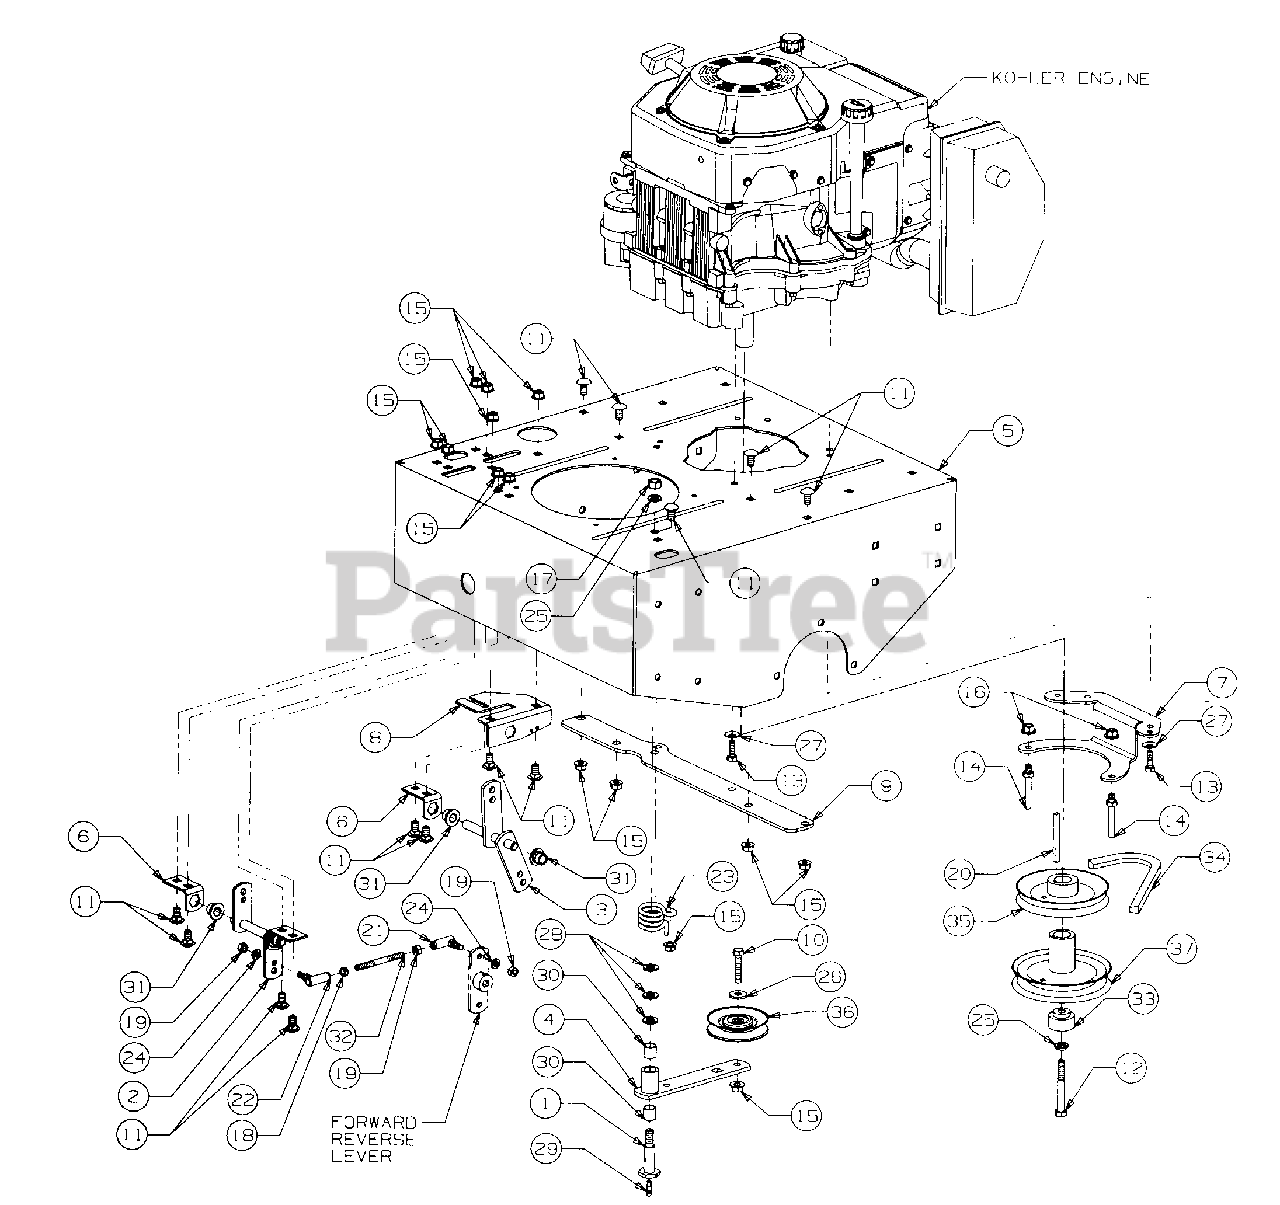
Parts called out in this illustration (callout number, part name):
1	Bolt, Shoulder
2	Lever, F/R Control
3	Lever, PTO Engagement
4	Arm Assy, Idler [Includes Ref No. 30 (Qty 2)]
5	Deck, Engine Mtg
6	Bracket, Lever Angle
7	Retainer, Belt Guide
8	Plate, Engagement Lever Mtg
9	Stiffener
10	Screw, Hex Cap, 3/6-16 X 1.75 Lg
11	Bolt Sht Nk Carriage, 3/8-16 X .75 Lg GR5
12	Screw, Hex Cap, M10 X 1.5 X 80 mm Lg
13	Screw, Hex Cap, M8 X 1.25 X 25 mm Lg
14	Stud, 3/8-16 X 2.68 Lg
15	Nut, Hex Flanged Lock, 3/8-16
16	Nut, Hex Flange Lock, 3/8-16 GR5
17	Nut, Hex, 7/16-14 GR5
18	Nut, Hex Jam, 5/16-24 LH Thread
19	Nut, Hex, 5/16-24 GR5
20	Key, Square, 1/4 X 3.0 Lg
21	Ball Joint, 5/16-24
22	Ball Joint, 5/16-24 LH Thread
23	Spring, Torsion
24	Washer, Lock, 5/16
25	Washer, Lock, 7/16
26	Washer, Special, .378 X 1.00 X .125 Thk
27	Washer, Bell, .340X .872 X .060 Thk
28	Washer, Flat, .469 X .875 X .105 Thnk
29	Fitting, Lube
30	Bearing, Sleeve
31	Bearing, Hex Flange
32	Rod, Control
33	Plug, Pulley
34	Belt, Transmission, 1/2 X 40.0 Lg
35	Pulley, Engine
36	Pulley, V-ldler
37	Pulley, PTO Drive
